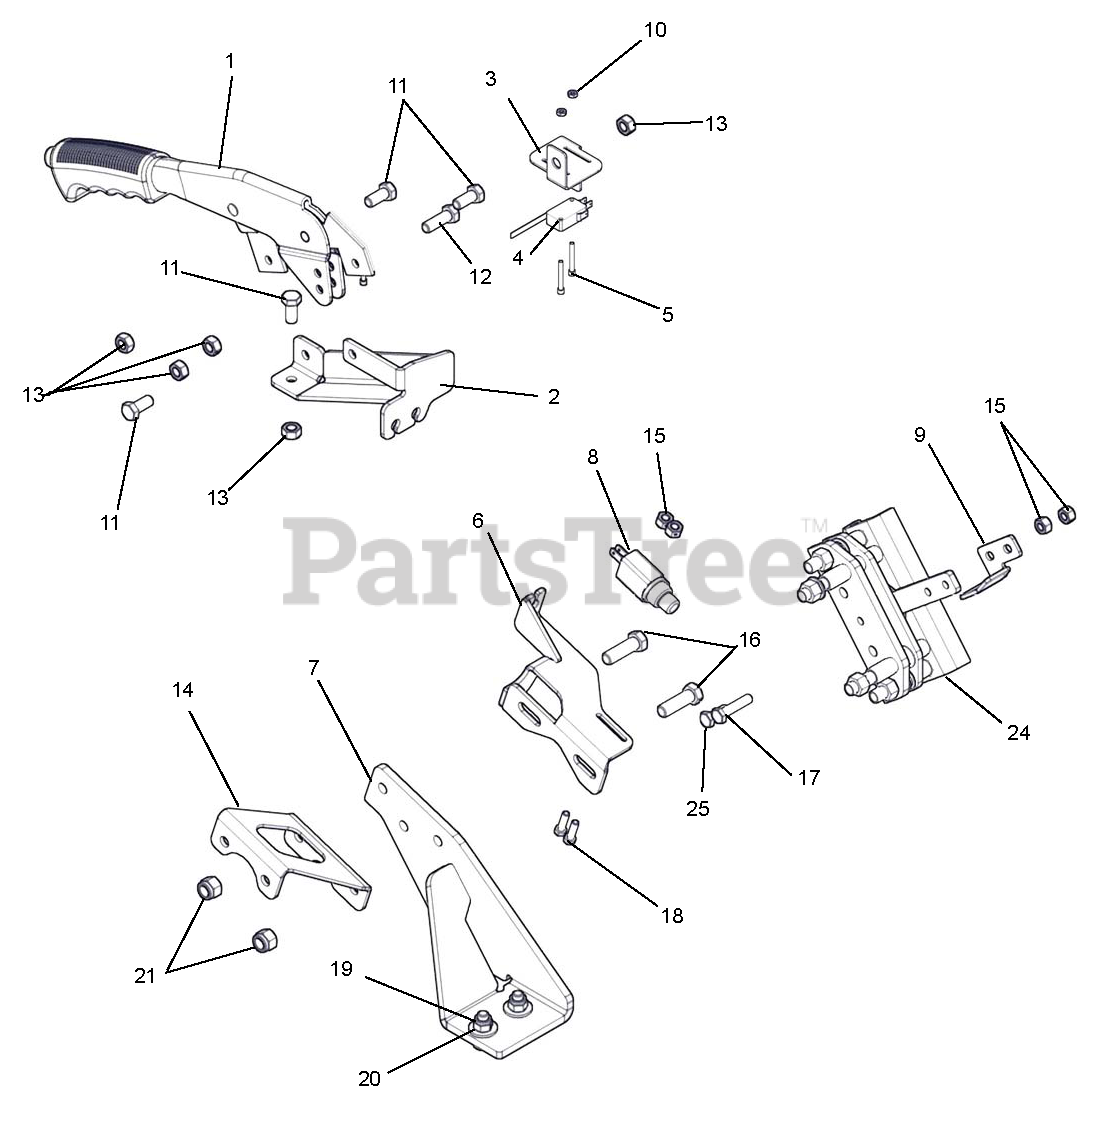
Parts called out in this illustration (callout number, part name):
1	PARK BRAKE LEVER
2	BRACKET,E-BRAKE MNT-BLK
3	BRACKET, PARK SWITCH
4	PARK BRAKE MICRO-SWITCH
5	HSHCS #4-40X1
6	CABLE MNT, PARK BRAKE
7	BRACKET, CALIPER MNT, BLCK
8	SWITCH-SINGLE POLE N.O.W/COVER
9	MOUNT,SWITCH,PARK BRAKE
10	NUT-HEX 4-40 YWZC GR5
11	@BLT-HEX .31-18X.75 GR5 YWZC
12	@BLT-HEX .31-18X1.00 GR5 YWZC
13	@NUT-LK-CTR .31-18 YWZC
14	BRACE, CALIPER MNT, P-BRAKE
15	@NUT-LK-CTR #10-24 YWZC
16	@BLT-HEX .38-16X1.25 GR5 YWZC
17	@BLT-HEX .25-20X1.25 GR5 YWZC
18	BLT-HEX 10-24X.75 PL GR2
19	@NUT-LK-NYL .312-18 YWZC
20	@WSHR-FL-STL.38X.875X.083 YWZC
21	@NUT-LK-NYL .38-16 YWZC
24	BRAKE CALIPER
25	@BLT-HEX .25-20X.75 GR5 YWZC
